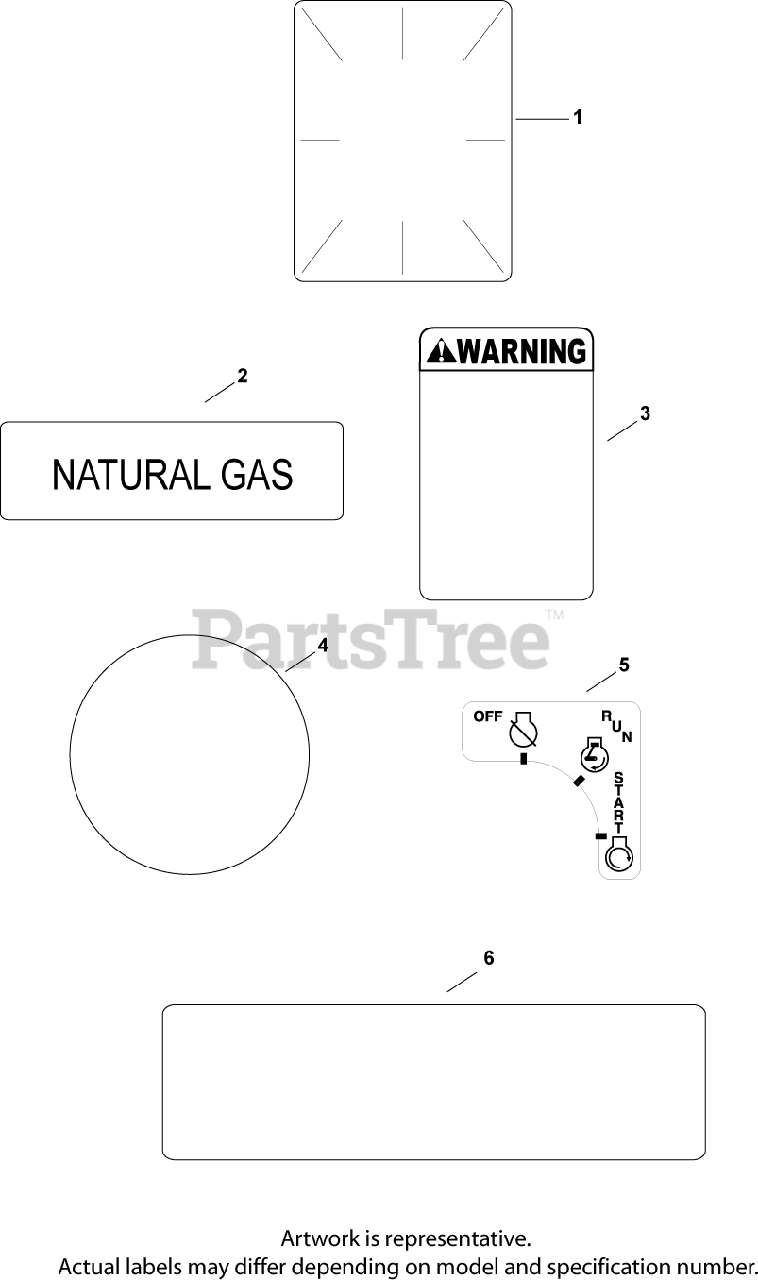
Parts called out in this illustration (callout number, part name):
1	DECAL, CLEAR LAMINATE USE 25 113 70-S
2	LABEL, NG SMARTSPARK - DISCONTINUED
3	DECAL, CO WARNING
4	DECAL, GRASS SCREEN USE 24 113 499-S
5	DECAL, KEY SWITCH
6	DECAL, COMMAND (GASEOUS) - DISCONTINUED
